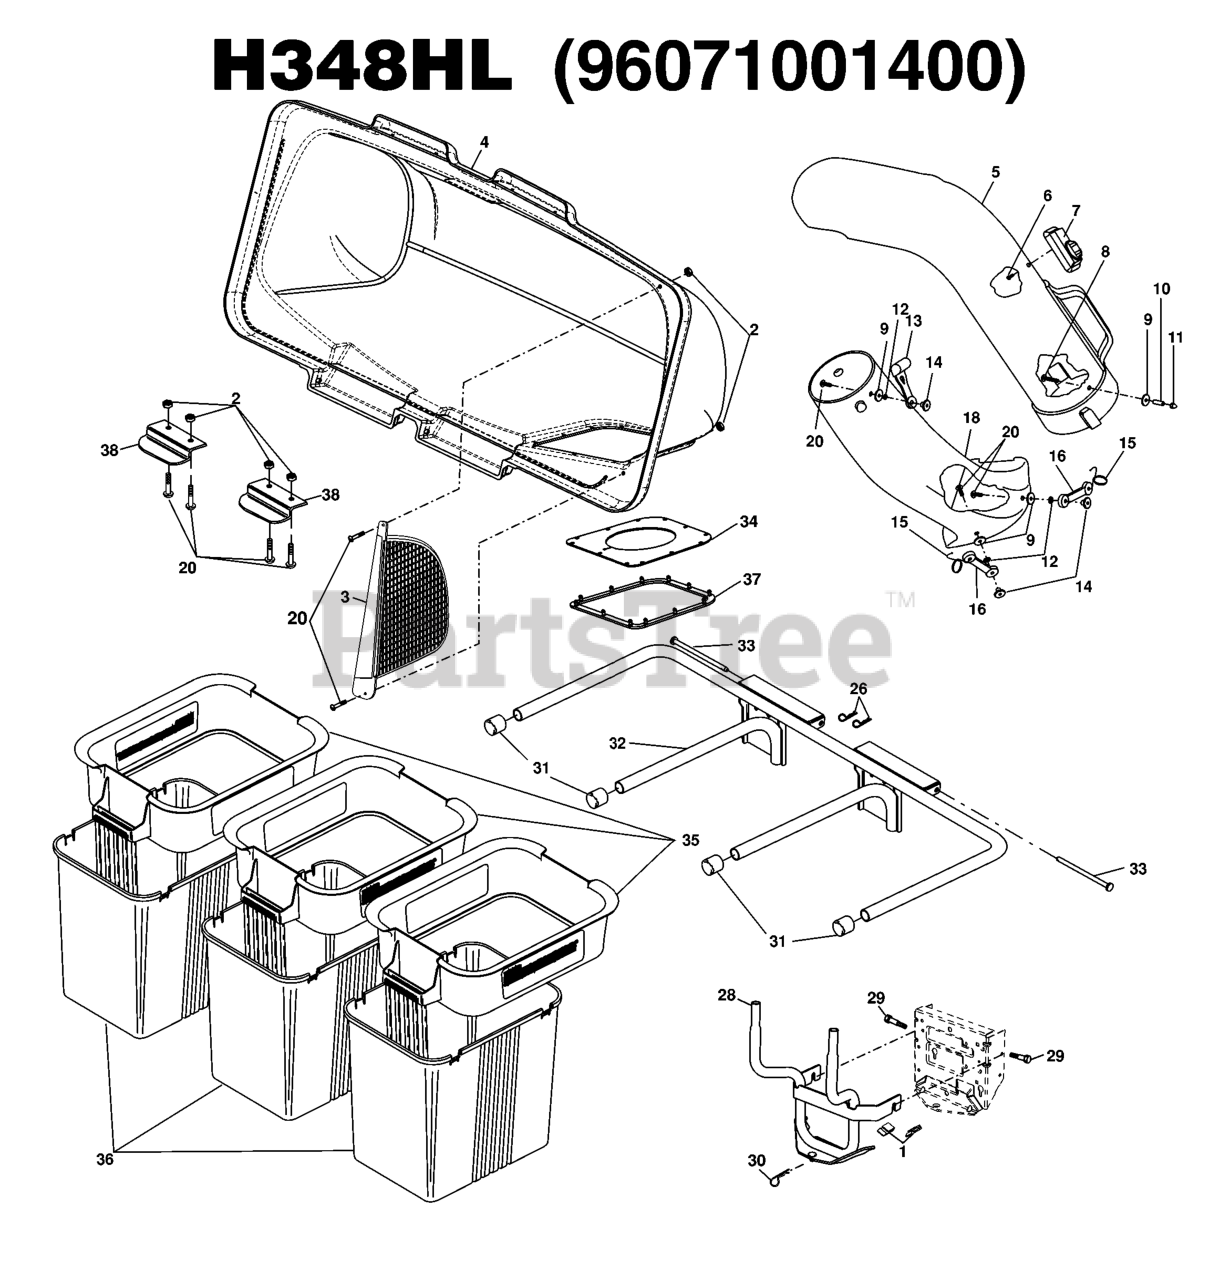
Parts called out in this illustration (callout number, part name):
1	ADAPTER.LT.3-BIN.QA.TEX
3	SCREEN.COVER.BAGGER
4	COVER.ASM.3BIN.GENERIC.
5	CHUTE.UPPER.42"
7	INDICATOR ASM BAG
8	SCREW
11	NUT
12	LOCKWASHER #10
13	LATCH.HOOD.
14	WELDNUT
15	HOOK LATCH
16	RUBBER LATCH
18	LOWER CHUTE FOR 42" BAGGER
20	SCREW
26	RETAINER-SPRNG RB
28	BRACKET.BAGGER.3-BIN.BLACK
29	SHOULDER BOLT, SELF-TAP
30	SPRING.RETAINER.YELLOW.ZINC
31	PLUG, TUBING END
32	BAGGER.ASM.FRAME.3BIN.BLACK
33	BAGGER.HINGE.PIN
34	SEAL.BAGGER.TOP.3-BIN.BLK
35	CONTAINER TOP
36	CONTAINER BOTTOM
37	GASKET.COVER.BAGGER
38	LATCH CER38
